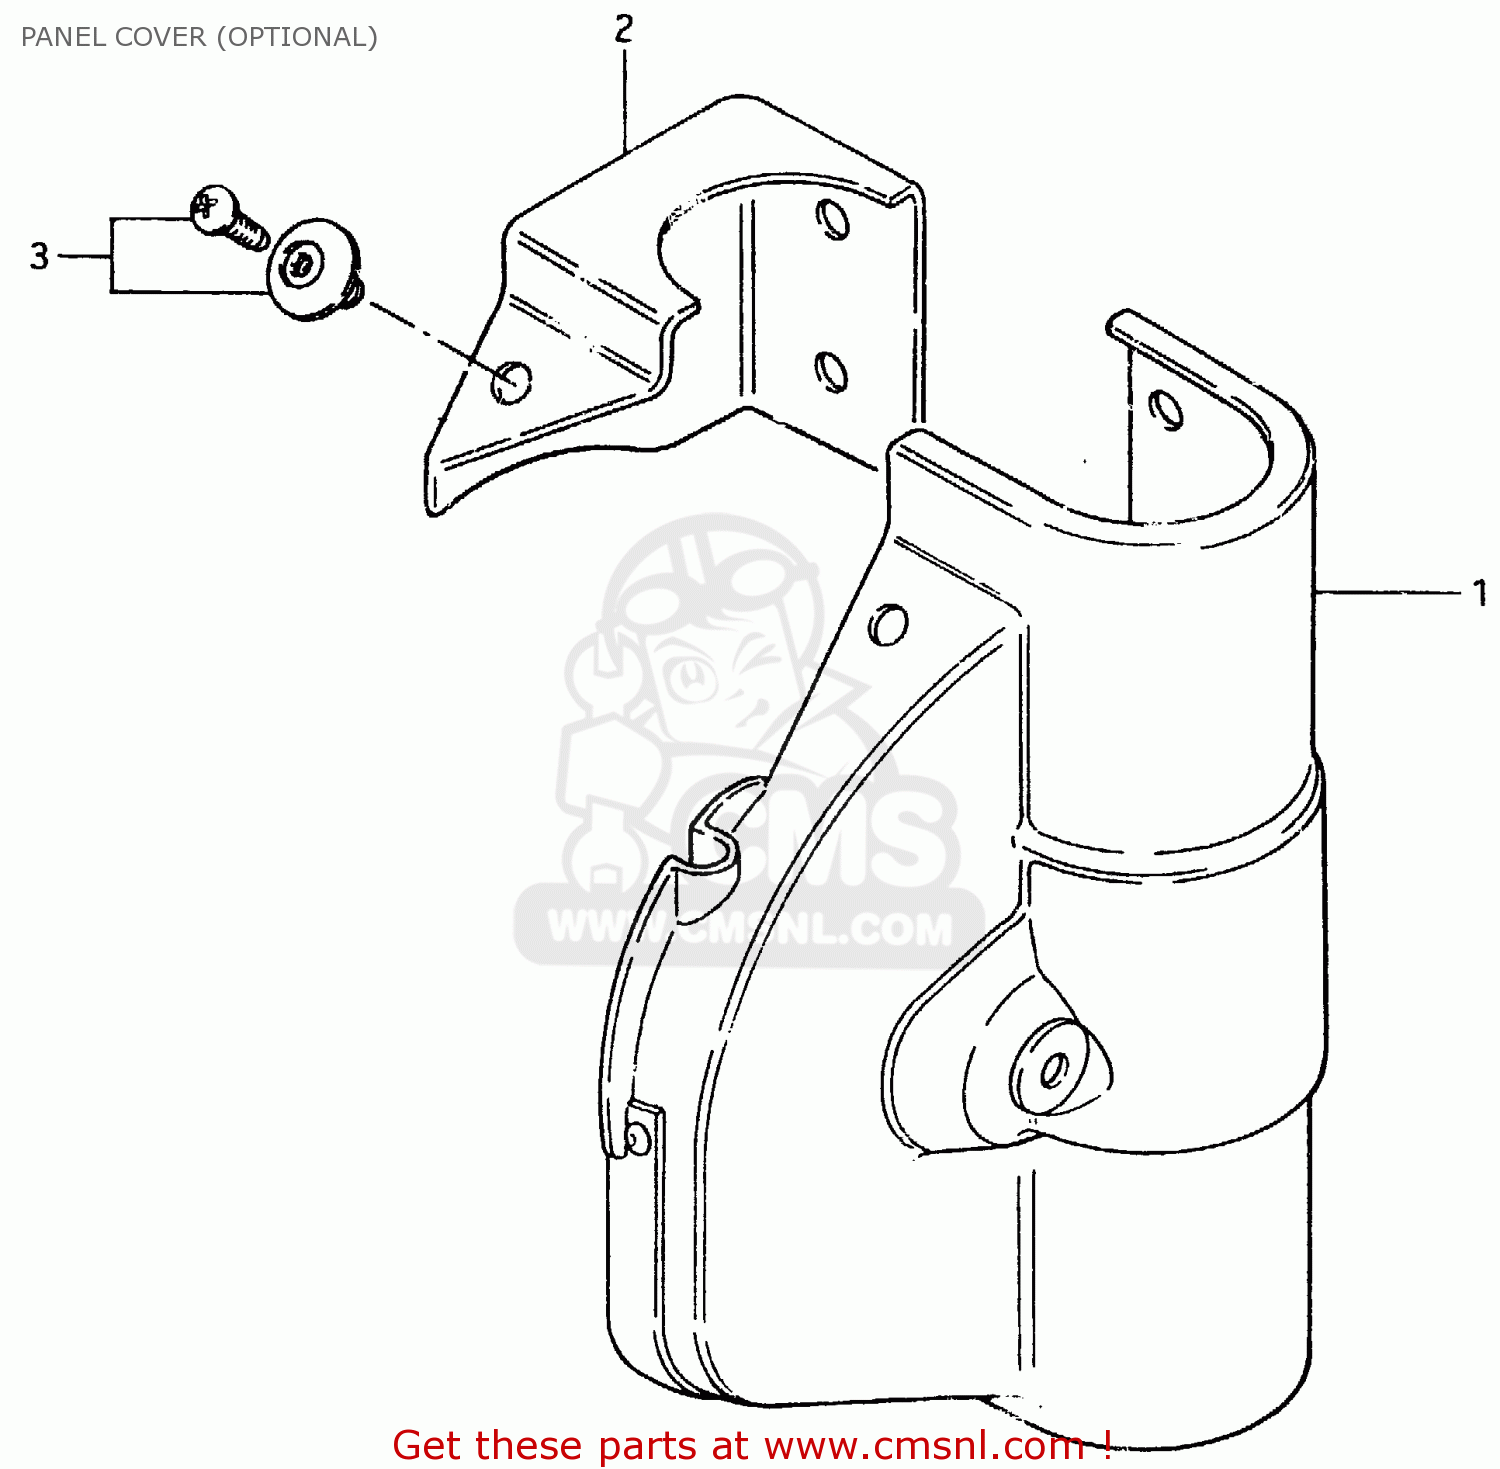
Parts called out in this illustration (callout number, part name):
1	COVER,FRONT HUB PANEL
2	CAP
3	CLIP(BLACK)
